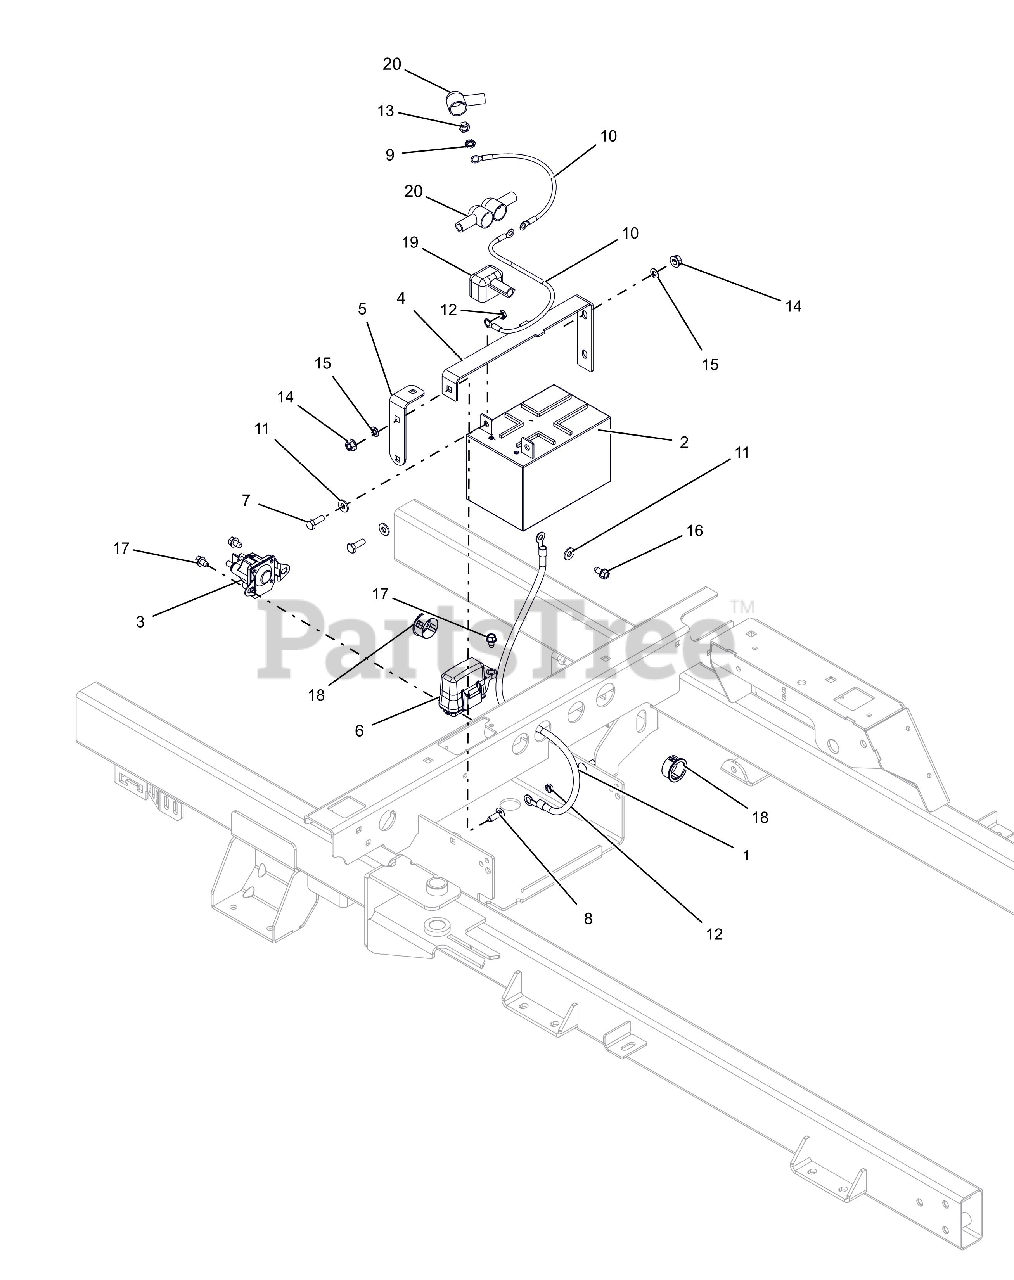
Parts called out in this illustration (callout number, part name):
1	CABLE-NEGATIVE BATTERY 24.00"
2	BATTERY, 12V 12A-190CCA
3	SOLENOID, STARTER (SEALED)
4	BRKT, BATTERY HOLD-DOWN
5	BRKT, BATTERY HOLD DOWN
7	@BLT-HEX .25-20X.75 GR5 YWZC
8	@BLT-RDHDSQNK .25-20X.75 G5YZ
9	@WSHR-LK-EXT.262X.502X.026YWZC
10	CABLE,POS W/2 1/4 RING 15.0 LG
11	@WSHR-FL-STL.281X.62X.065 YWZC
12	NUT, 10-24 KEPS
13	@NUT-HEX .25-20 YWZC
14	@NUT-LK-TOP-FLG .25-20 YWZC
15	NUT-PUSH .25X.50 O.D.
16	SCR-TAP .25-20X.50 HWH TR YWZ
17	@SCR-TAP .25-20X.37 HWH YWZ TR
18	BSHG, PANEL SNAP .937X1.11X.56
19	INSULATOR
20	BOOT, EYELET TERMINAL
